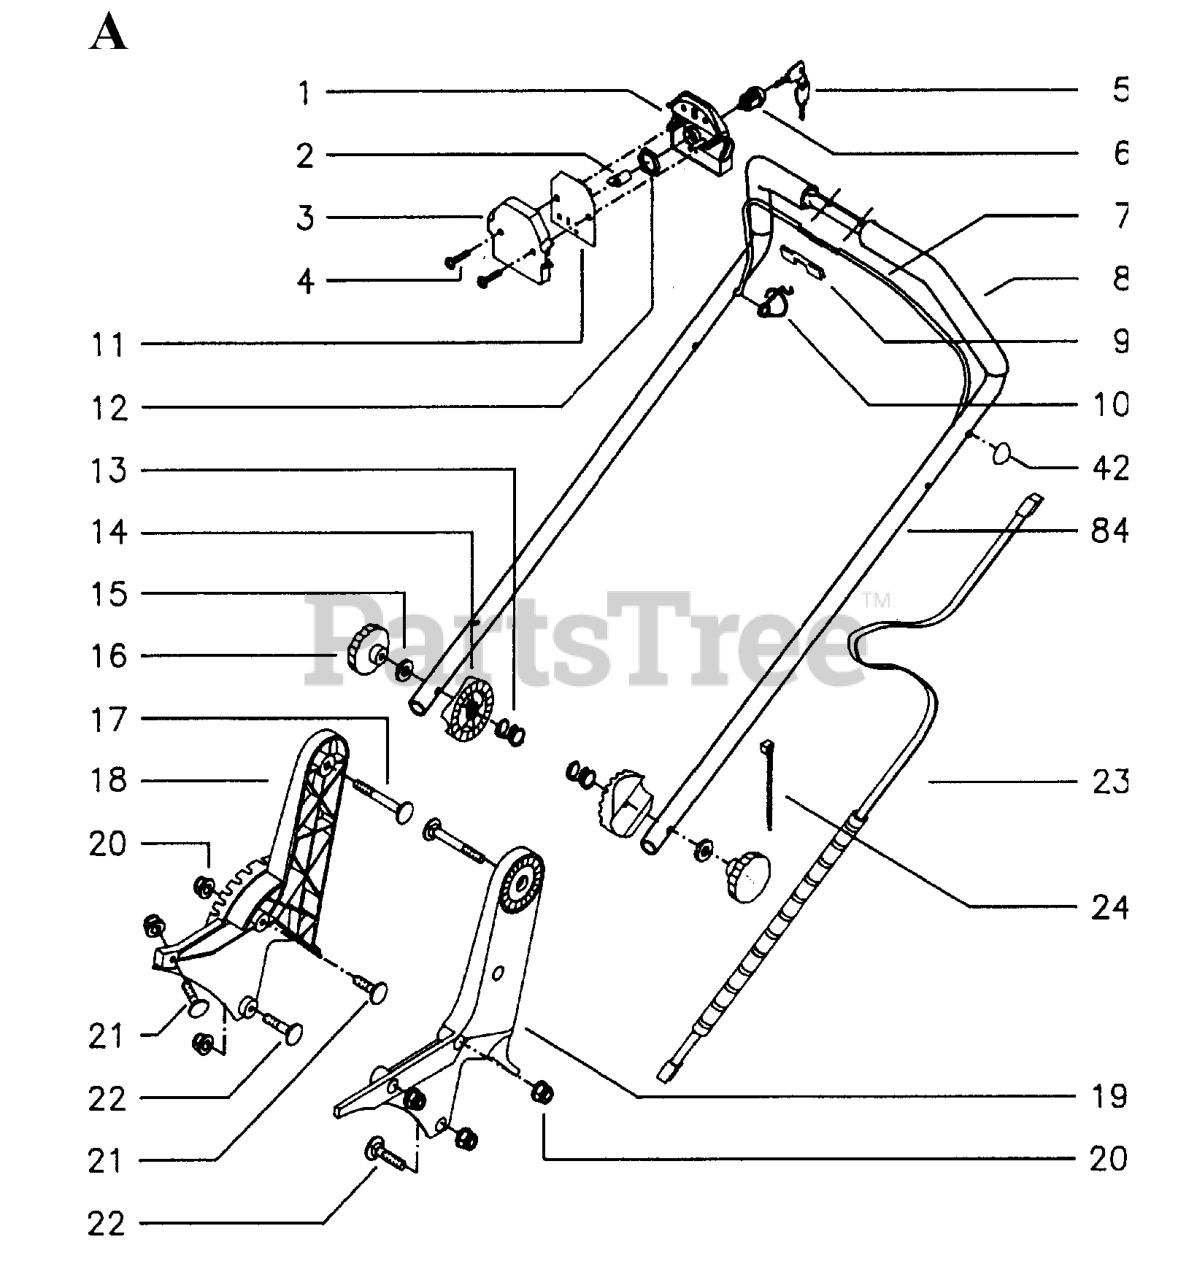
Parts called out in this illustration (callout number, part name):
8	VIBRATION DAMPENER
20	FLANGE NUT
21	REPL BY 515 71 16-20
